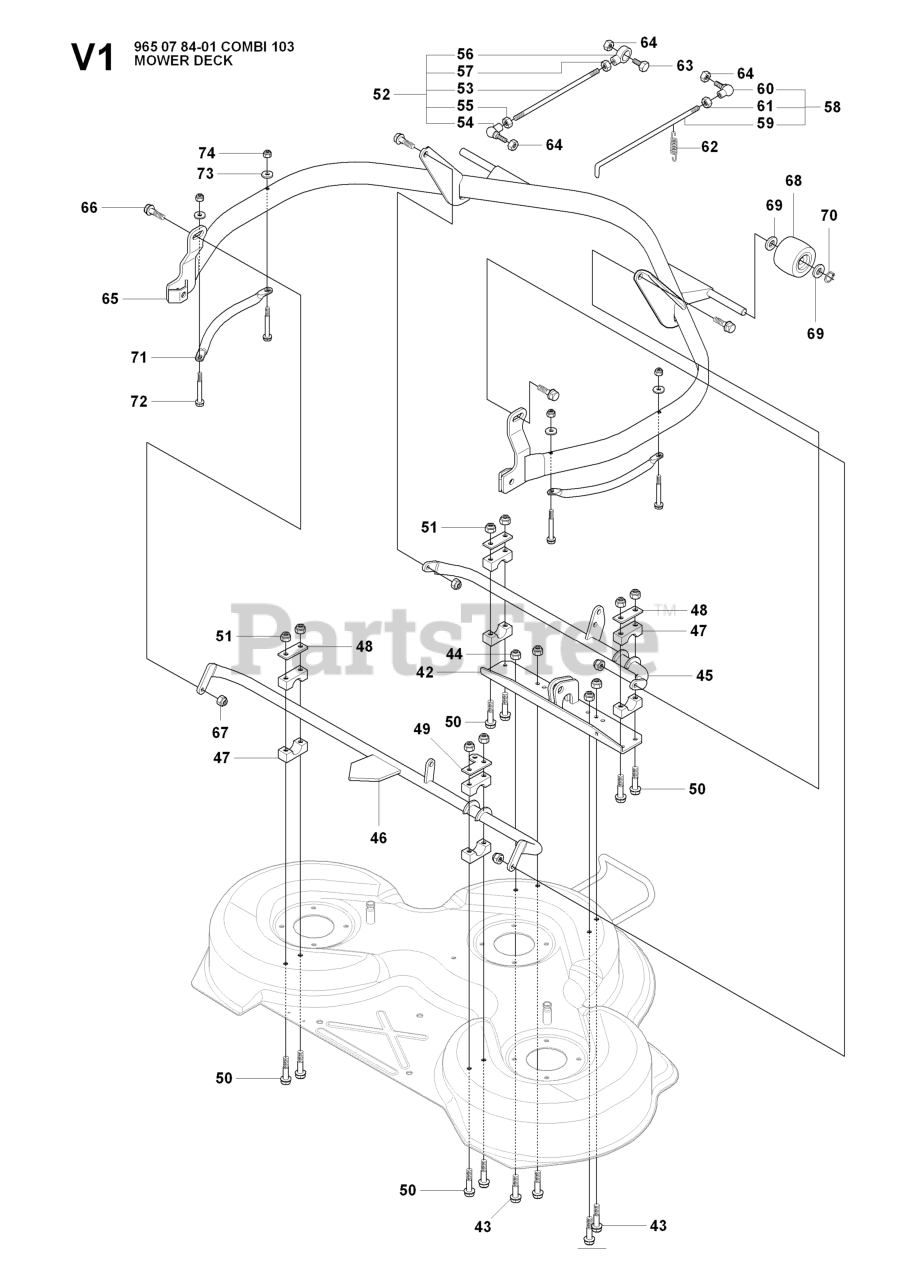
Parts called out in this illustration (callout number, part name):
44	LOCKNUT M8
51	LOCKNUT M8
52	PARALLEL RODY ASSY
57	NUT
58	CLUTCH ROD ASSY
64	NUT
65	PROTECTIVE TUBING
67	LOCKNUT M8
68	DECK ROLLER, FRONT
70	RETAINING RING SGA 15
73	WASHER
74	LOCKNUT M6
